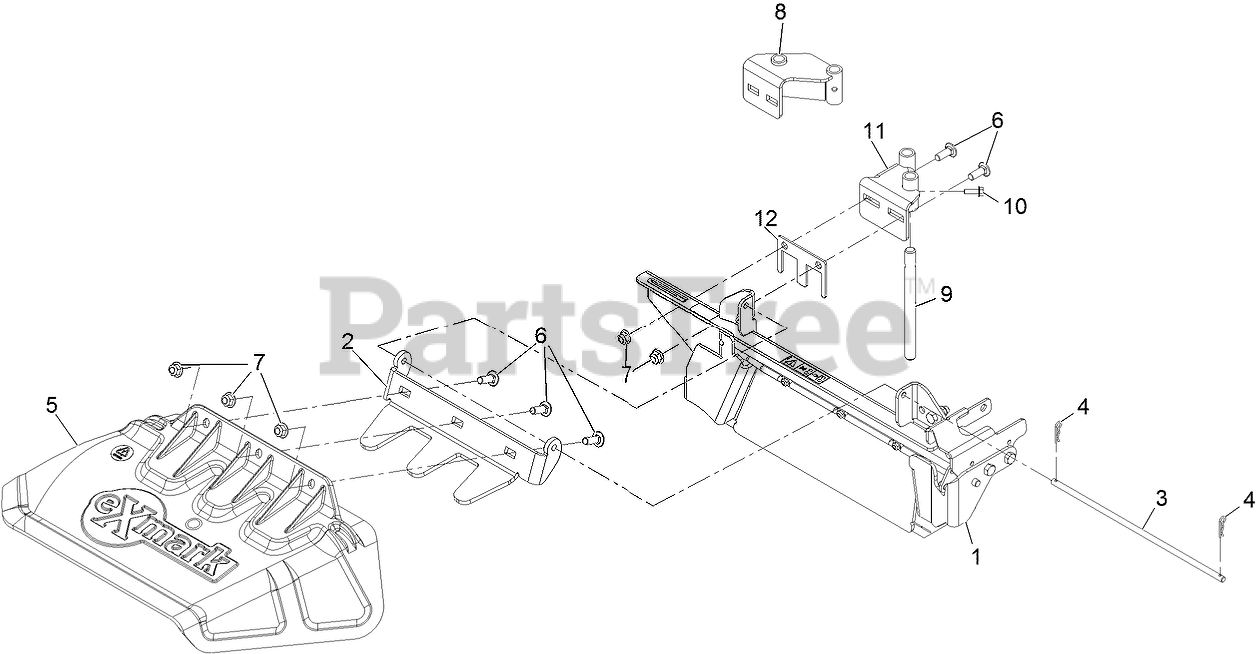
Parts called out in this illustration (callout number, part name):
1	ASM, Ocd Gate
2	MOUNT, DISCHARGE CHUTE
3	PIN,CHUTE
4	PIN-COTTER
5	CHUTE,DISCHARGE
6	SCREW-CARR
7	NUT-HF, NI
8	Ocd Mount ASM [red]
9	PIN-MOUNT, OCD
10	SCREW-HHF
11	WELDMENT, OCD MOUNT
12	SHIM-OCDWB
